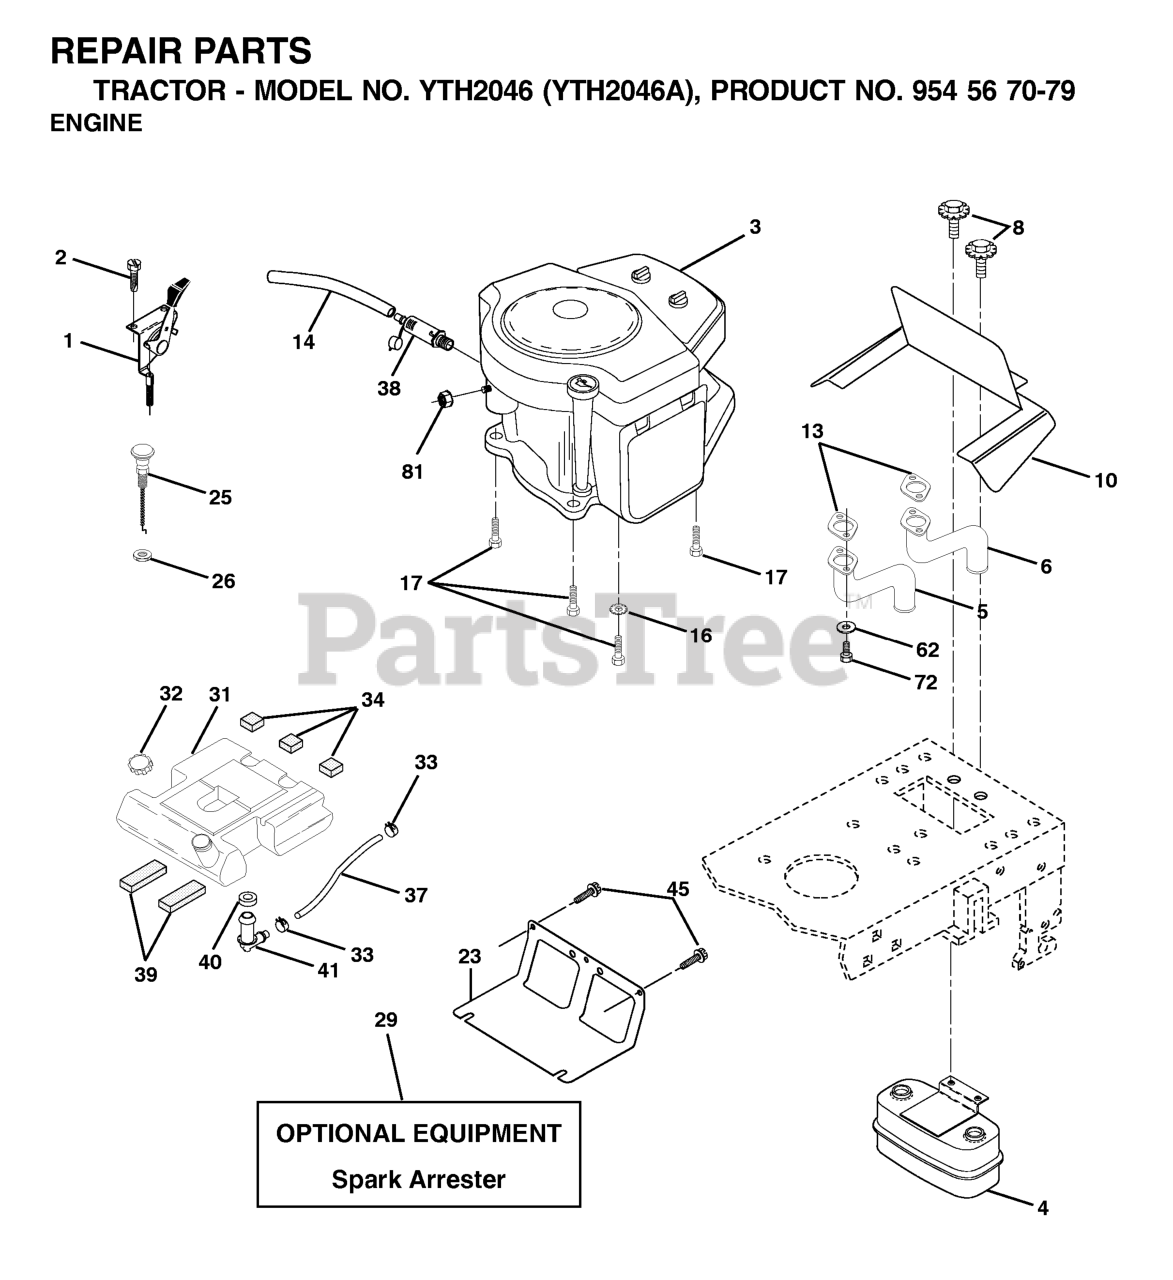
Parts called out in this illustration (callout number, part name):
1	CONTROL, THROTTLE
2	SCREW LT
4	MUFFLER.TWIN.CYL.LOW.TONE
5	RP.EXHAUST.TUBE.LH.BS/TWIN
6	EXHAUST.TUBE.RH.BS/TWIN
8	BOLT.5/16-18UNCX3/4 W/SEMS.BLK
10	SHIELD.BROWNING.B&S
13	GASKET.MUFFLER
14	TUBE, DRAIN OIL ASM.
16	LOCKWASHER
17	SCREW LT
23	SHIELD.BROWNING.DBR.GUARD
25	CONTROL, CHOKE
26	Nut Keps 3/8 - 24 UNF
29	KIT.SPARK ARRESTOR 794945 B&S
31	FUEL TANK 3.5G
32	FUEL CAP
33	HOSE CLAMP
34	PAD-SPACER LT
37	REPL BY 532 00 85-43
38	PLUG, OIL DRAIN EASY
39	PAD IDLER TI
40	BUSHING OUTLET T
41	STEM FUEL TANK
45	SCREW, 3/8-16X3/4
62	WASHER.LOCK.HVY.HLCL.SPR.5/16
72	SCREW
81	NUT
